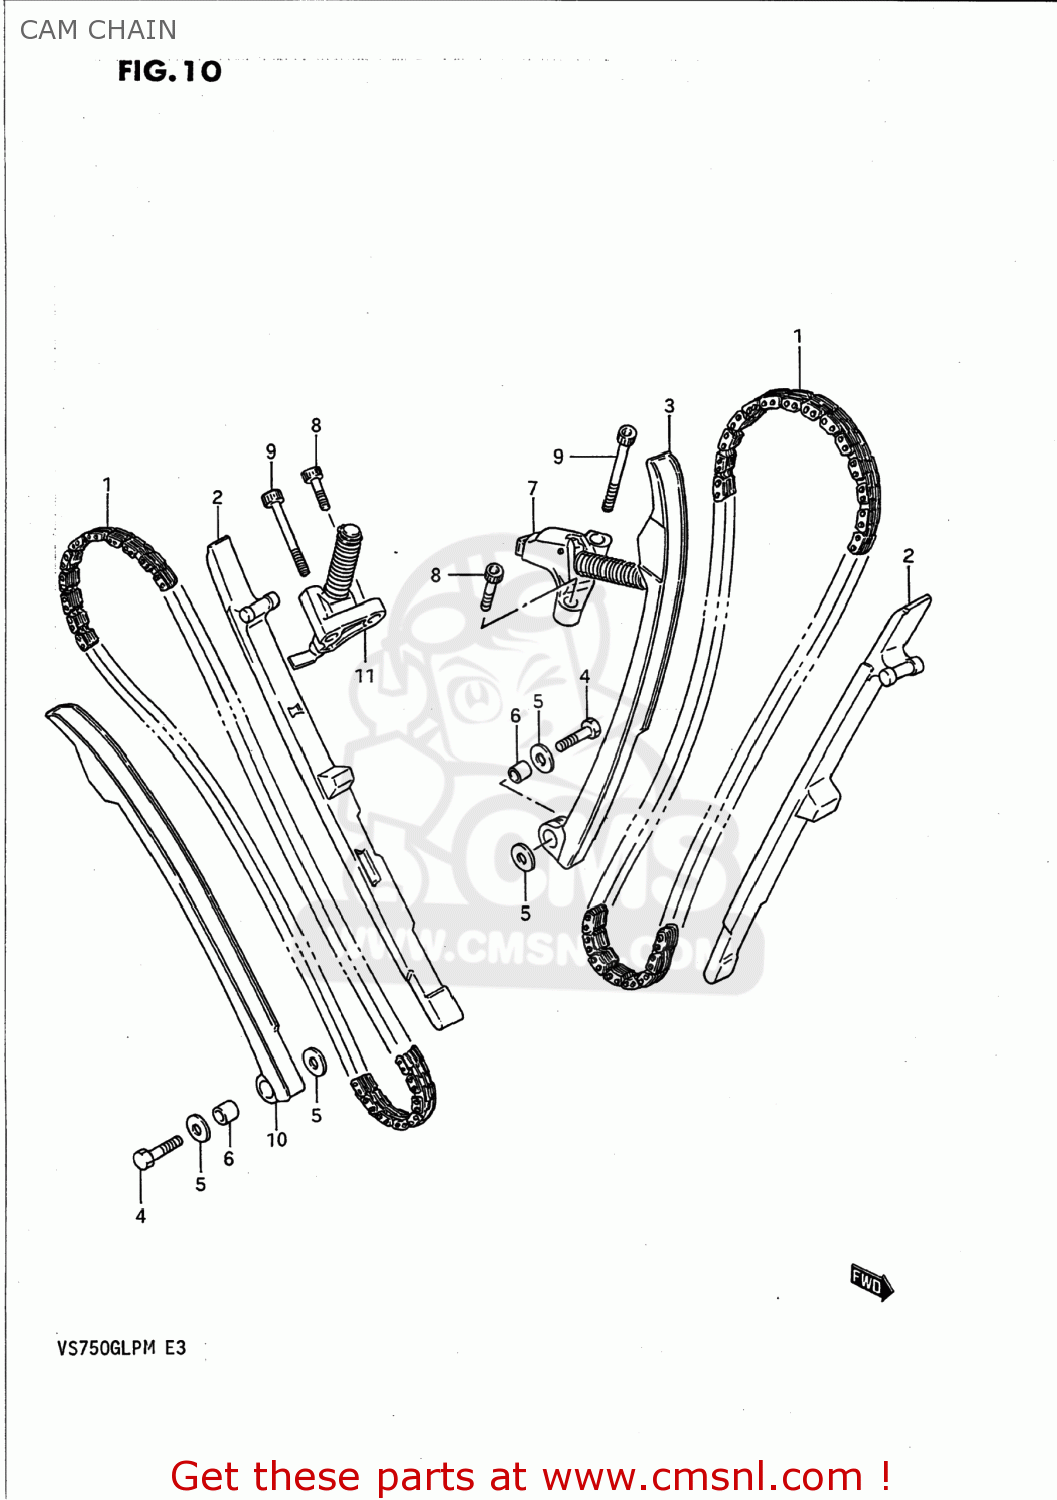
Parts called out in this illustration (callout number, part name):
1	CHAIN,CAMSHAFT DRIVE
2	GUIDE,CAM CHAIN
3	TENSIONER,FR CAM CHAIN
4	BOLT(6X26)
5	WASHER
6	SPACER(6X11X11)
7	ADJUSTER ASSEMBLY,FRONT TENSIONER
8	BOLT
9	BOLT
10	TENSIONER,RR CAM CHAIN
11	ADJUSTER ASSEMBLY,REAR TENSIONER
